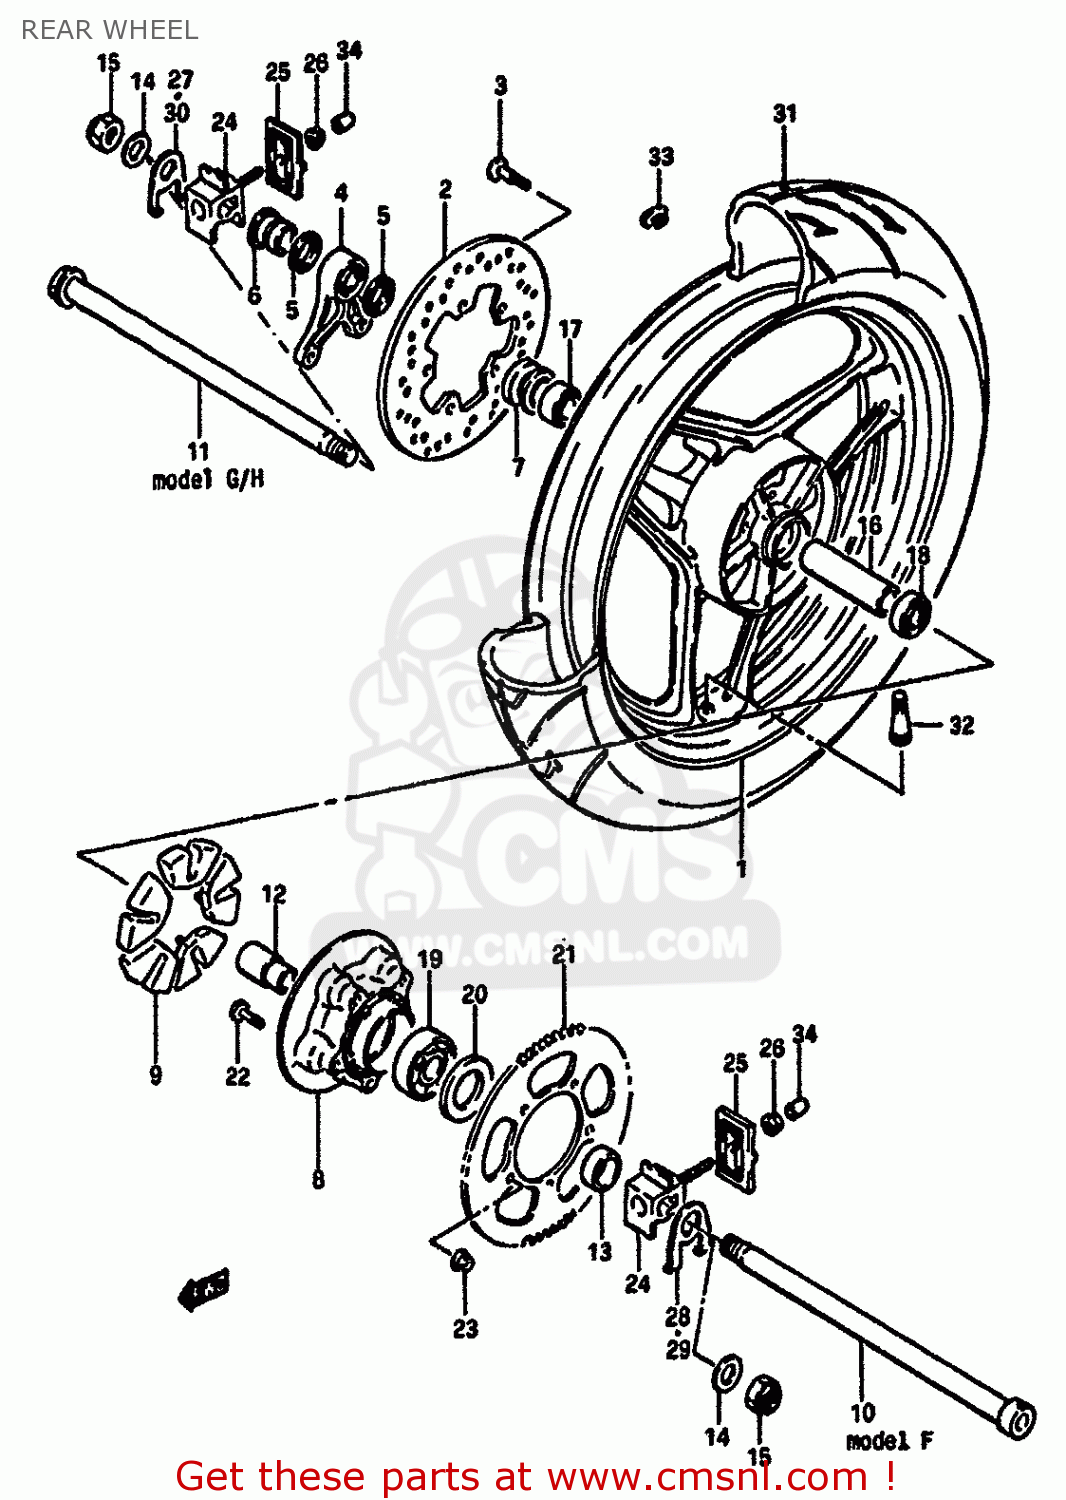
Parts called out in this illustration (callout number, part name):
1	WHEEL,REAR
2	DISC,RR BRAKE
3	BOLT
4	BRACKET,RR CALIPER
5	SEAL,OIL(28X35X5)
6	SPACER,RR CALIPER BRACKET
7	SPACER,RR AXLE,R
8	DRUM,REAR SPROCKET MOUNT
9	ABSORBER,RR HUB SHOCK
10	AXLE,REAR
11	AXLE,RR
12	RETAINER,RR HUB BEARING
13	SPACER,RR AXLE,L
14	WASHER
15	NUT
16	SPACER,REAR WHEEL HUB
17	BALL BEARING
18	BEARING
19	BEARING(25X62X17)
20	SEAL,OIL(35X62X8)
21	SPROCKET,RR(NT:42)
22	BOLT
23	NUT
24	ADJUSTER,CHAIN
25	PLATE,CHAIN ADJUSTER GEAR
26	NUT
27	WASHER,CHAIN ADJUSTER
28	WASHER,CHAIN ADJUSTER
29	WASHER,CHAIN ADJUSTER
30	WASHER,CHAIN ADJUSTER
31	TIRE
32	VALVE,TIRE
33	BALANCER,WHEEL
34	CAP,CHAIN ADJUSTER
